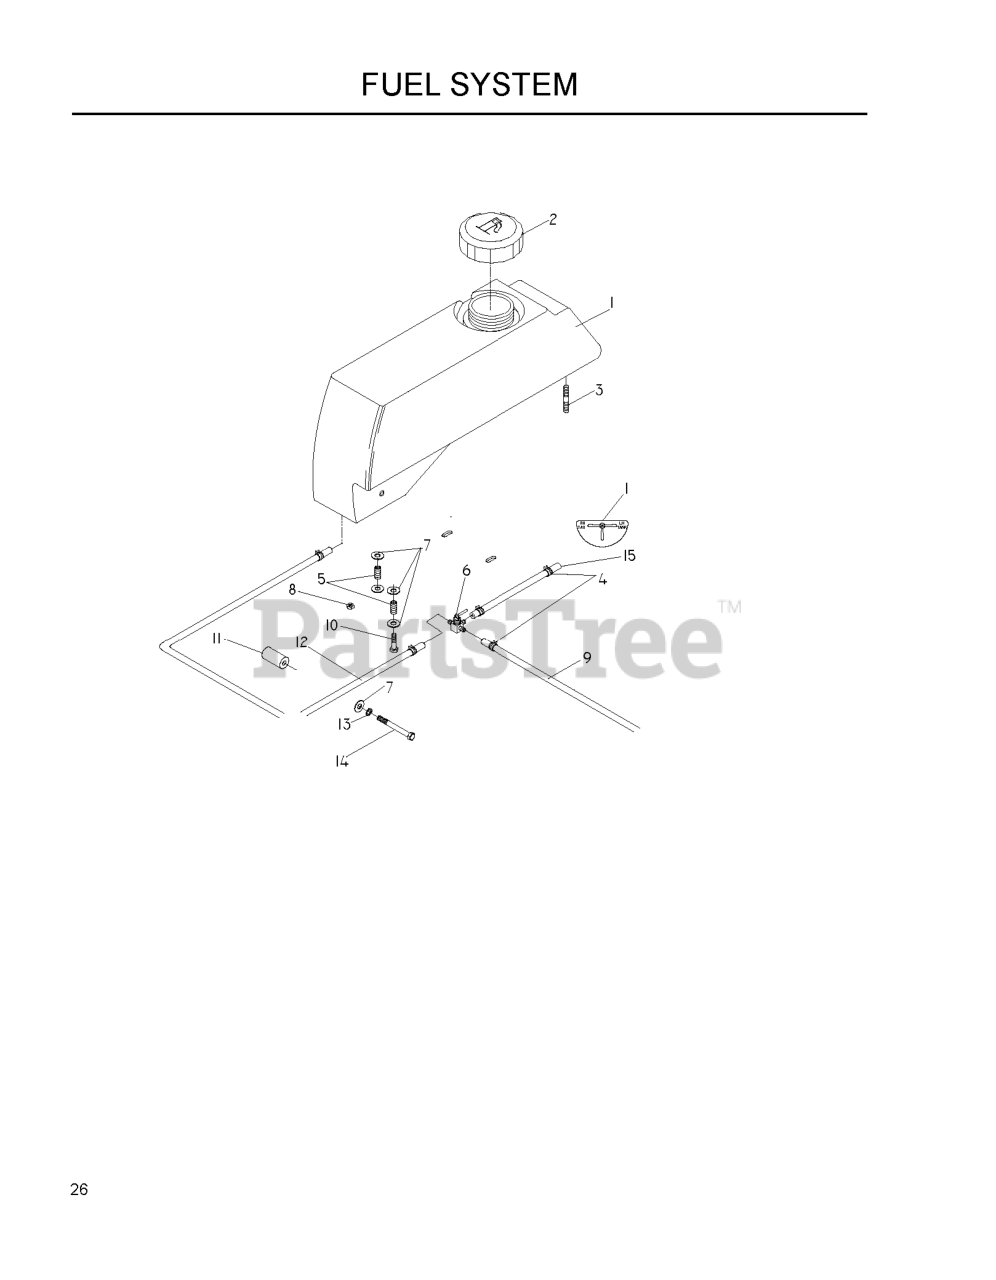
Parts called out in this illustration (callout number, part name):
1	FUEL TANK RT
1	LEFT TANK W/CUP HOLDER
2	FUEL CAP ANTI-SPLASH
3	STUD, 5/16C
4	HOSE CLAMP
6	FUEL VALVE
7	WASHER 5/16 FLAT
8	NUT 5/16C CENTERLOCK
10	HCS 5/16C X 1
11	TANK SPACER
13	WASHER.LOCK.HVY.HLCL.SPR.5/16
14	HCS 5/16C X 4
15	FUEL LINE 13"
16	DECAL, FUEL VALVE
